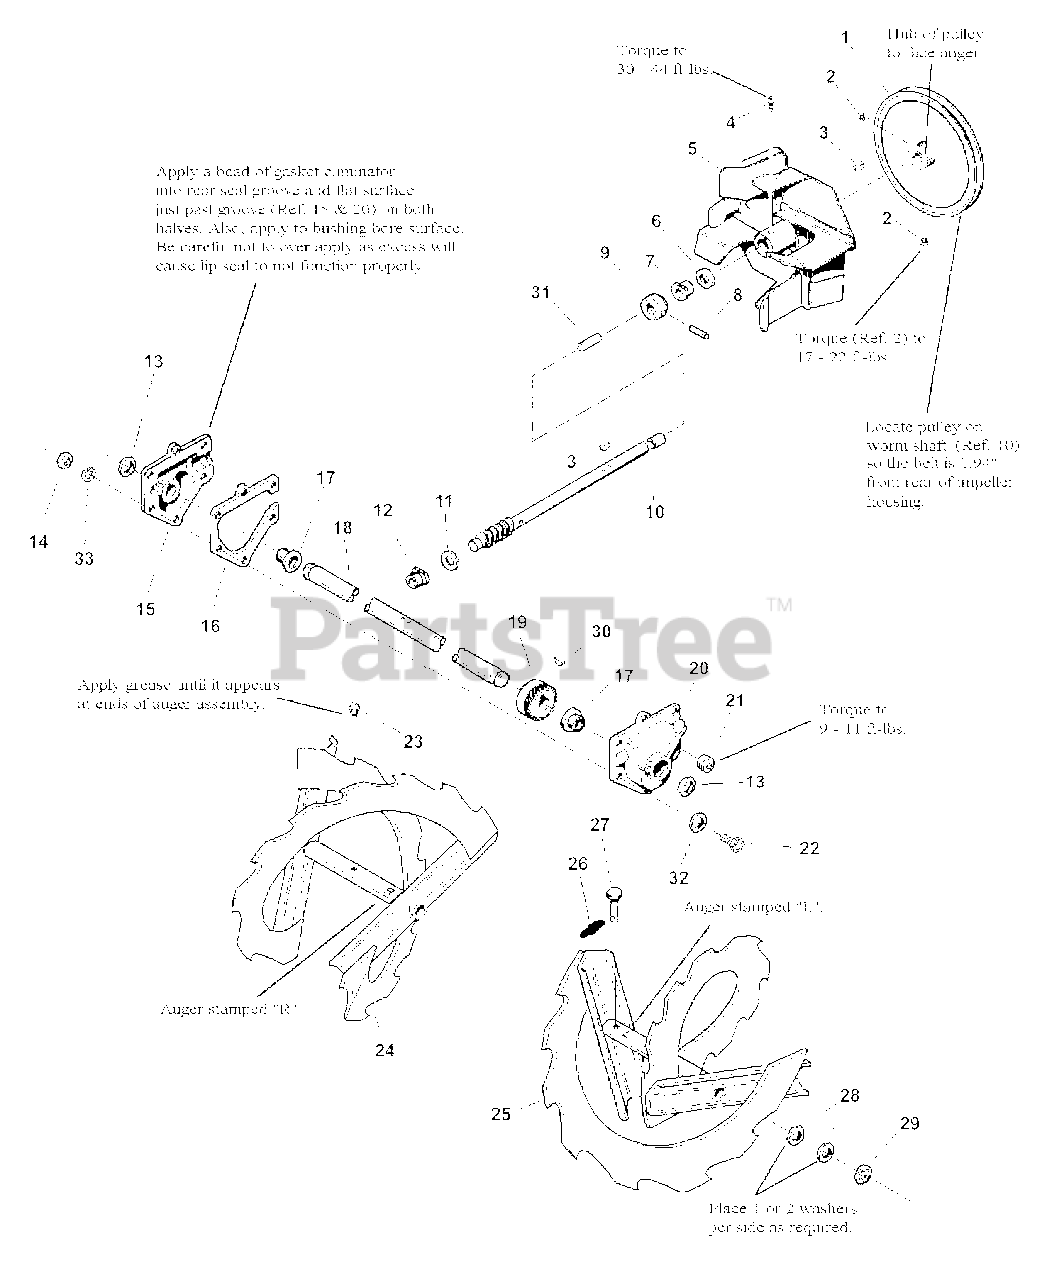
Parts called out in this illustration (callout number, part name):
1	PULLEY, Auger Input
2	SET SCREW, 5/16-18 x 1/2" Square Head Cup Point
3	KEY, 3/16 x 3/4" Woodruff
4	SET SCREW, 3/8-16 x 1/2" Square Head
5	WELDMENT, Impeller
6	OIL SEAL
7	BUSHING
8	PIN, Drive-Loc, 3/16 x 1-1/2"
9	COLLAR, Thrust
10	SHAFT, Rolled Worm
11	WASHER, Thrust (.562 ID x 1.000 OD x .030/.032 Thick)
12	FLANGE, Bushing
13	OIL SEAL
14	NUT 1/4-20 Hex
15	GEAR CASE, LH- Intermediate
16	GASKET, Gear Case
17	BUSHING
18	SHAFT, Auger, 22"/24"
19	GEAR, Worm
20	GEAR CASE, RH- Intermediate
21	PIPE PLUG, 1/8-27 NPTF 3/4 Taper x .31 Long Hex Drive
22	SCREW, 1/4-20 x 7/8" Hex Head Cap, GR 5
23	FITTING, Grease
24	WELDMENT, 22" Auger, RH
25	WELDMENT, 22" Auger, LH
26	COTTER PIN, 1/4" Self Locking
27	SHEAR PIN, .248 ID x 1-3/4" Long
28	WASHER
29	RING, External Retaining (for .75 dia. Shaft)
30	KEY, #605 Woodruff
31	TUBE, Low Density Polyethylene Extruded
32	FLAT WASHER, .268 ID x .591 OD x .063 Thick
33	WASHER, 1/4" Split Lock
